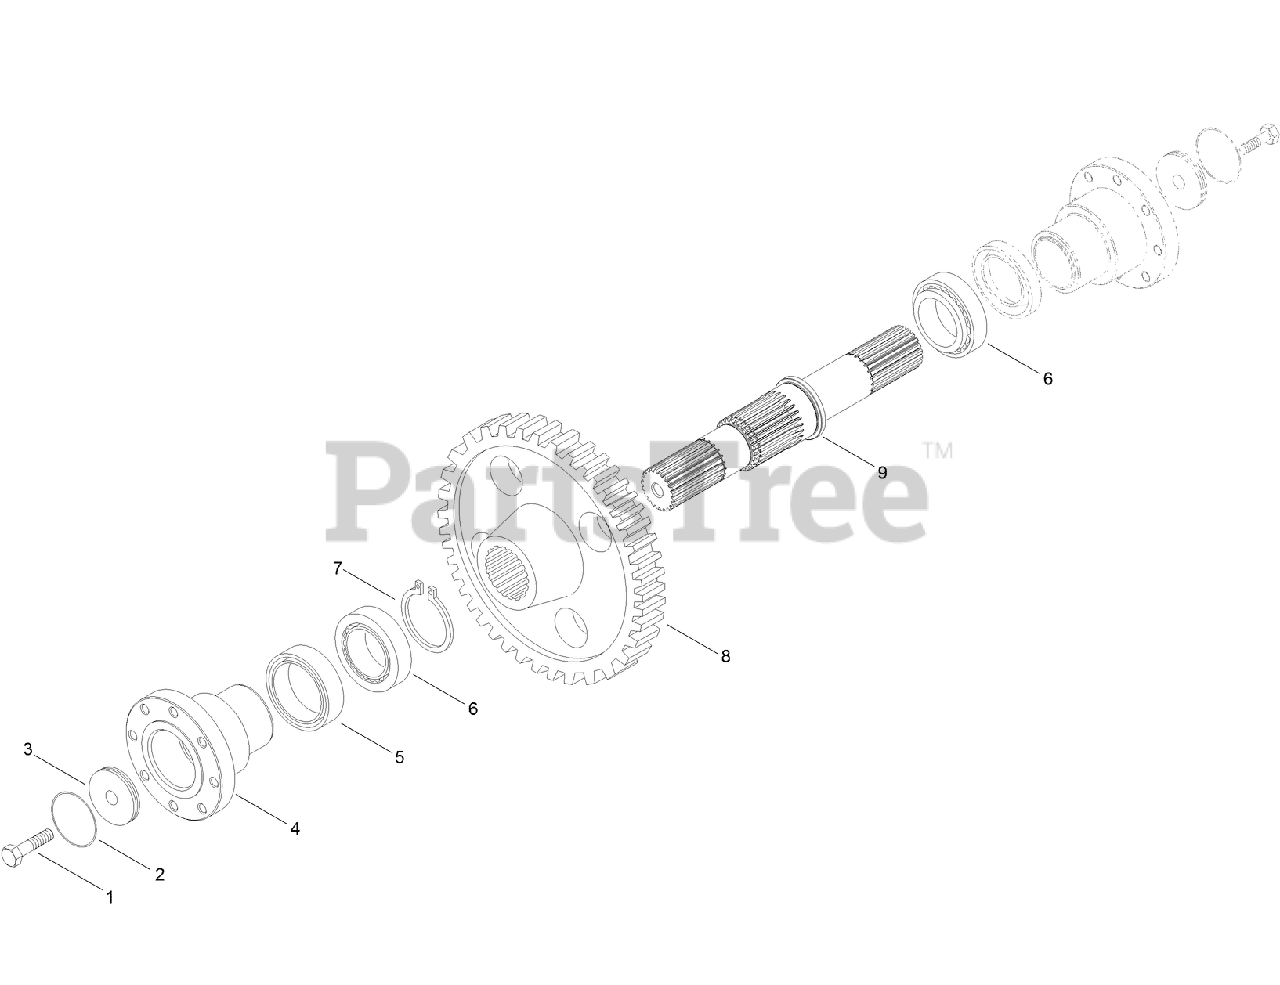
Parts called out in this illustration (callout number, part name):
5	SEAL-LIP
6	BEARING-TAPER
7	RING-RETAINING
8	GEAR-DRIVEN, DROP SET
9	SHAFT-OUTPUT
